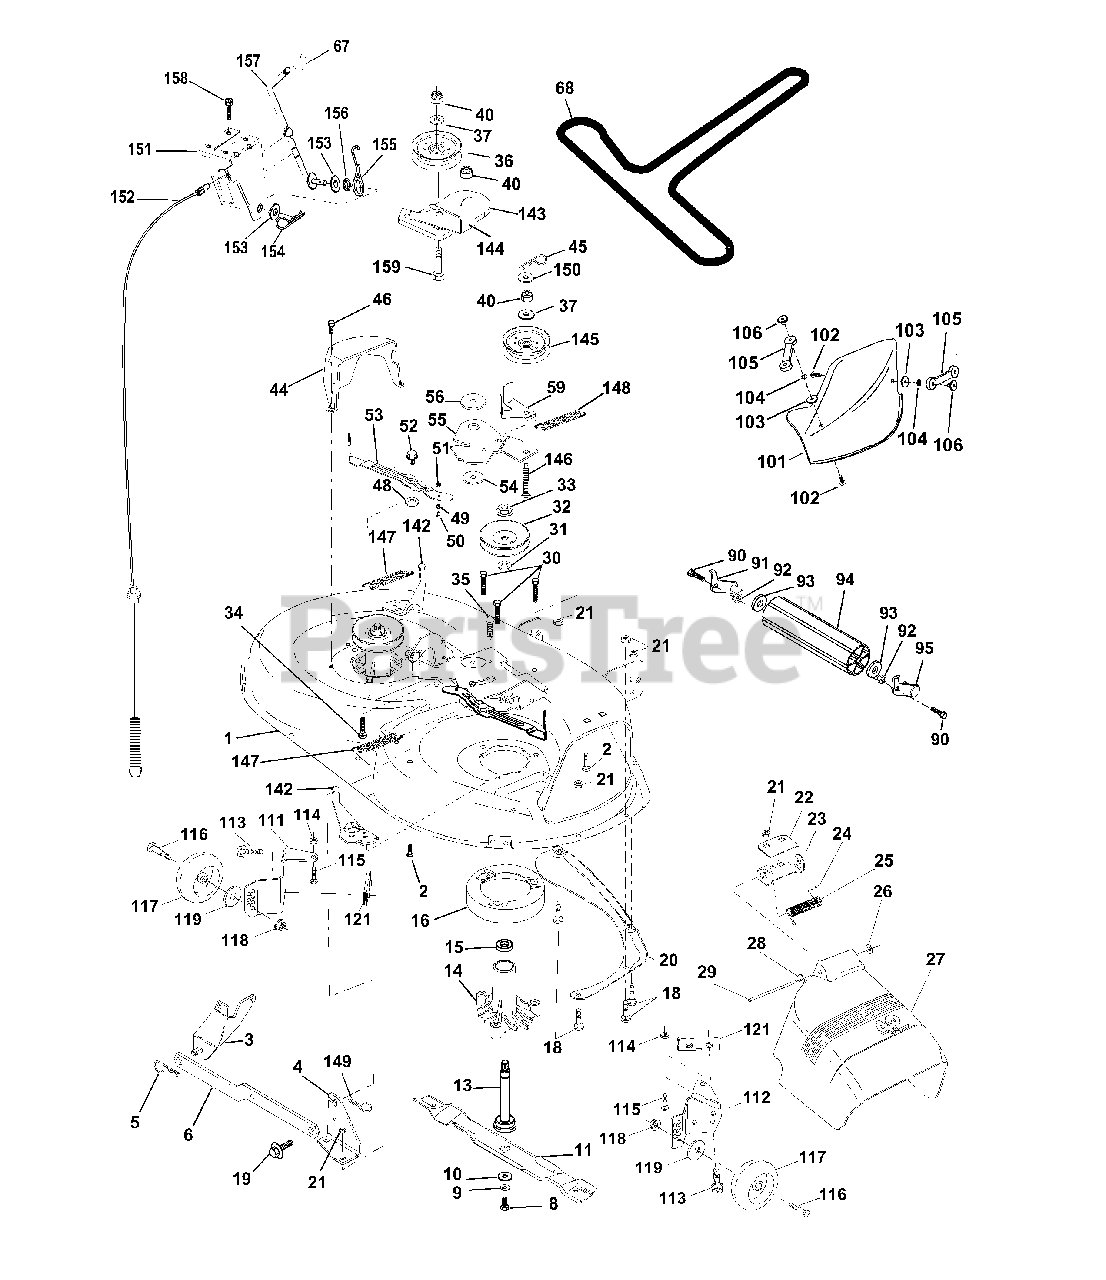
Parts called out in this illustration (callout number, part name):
1	Mower Deck Assembly, 42"
2	Bolt
3	Bracket Asm Fr. Sway Bar 3/42
4	Bracket Asm Deck 42" Sway Bar
5	Retainer Spring
6	Arm, Suspension, Rear
8	Bolt 3/8-24 x 25 Grade 8 patched
9	Washer, Lock
10	Washer,Hardened
11	Blade, Mulching 42"
11	Blade Mower 42" Hi-Lift
13	Shaft Assembly, Mandrel, Vented
14	Housing, Mandrel, Vented
15	Bearing, Ball, Mandrel
16	Stripper, Mandrel Deck
18	Bolt, Carriage 5/16-18 x 5/8
19	Bolt, Shoulder
20	Baffle, Vortex
21	Nut
22	Stiffener Bracket
23	Bracket, Deflector Mower 42"
24	Cap, Sleeve 80 x 112 Blk Mower
25	Spring, Torsion, Deflector 2 52
26	Nut, Push Phos & Oil
27	Shield, Deflector 42" Blk
28	Washer 11/32 x 5/8 x 16 Gauge
29	Rod, Hinge 42" 6 75 W/G
30	Screw Thdrol Washer Head
31	Washer, Spacer Mower Vented
32	Pulley, Mandrel
33	Nut, Toplock 9/16
34	Bolt
35	Fastener, Christmas Tree
36	Pulley, Idler, Flat
37	Washer 13/32 x 13/16 x 16 Gauge
40	Nut
44	Guard, Mandrel, LH
45	Retainer
46	Screw, Thdrol 1/4-20 x 5/8 T
48	Washer,Hardened
49	Roller Assembly, Cam Follower
50	Bolt, Shoulder #10-24 Grade 5
51	Locknut
52	Bolt, Shoulder 5/16-18 UNC
53	Arm Assembly, Pad, Brake
54	Washer,Hardened
55	Arm, Idler
56	Spacer, Retainer
59	Guard TUV Idler
67	Knob
68	V-Belt, 42" Mower
90	Bolt Fin Hex 3/8-16 Unc x 1
91	Bracket Asm. Noseroller LH
92	Nut, Lock, Hex W/Ins 3/8-16 UNC
93	Washer 17/32 x 7/8 x 16 Ga.
94	Roller, Nose
95	Bracket Asm. Noseroller RH
101	Mulcher Cover
102	Screw
103	Washer, Flat
104	Washer, Lock
105	Latch Assembly
106	Nut, Weld
111	Bracket, Gauge, Wheel LH
112	Bracket, Gauge, Wheel RH
113	Screw Tapping 5/16-18 Unc
114	Nut, Keps 5/16 - 18 UNC
115	Bolt, Carriage 5/16-18 x 1/2
116	Bolt, Shoulder
117	Wheel, Gauge
118	Nut Centerlock 3/8-16
119	Washer 3/8 x 7/8 x 14 Ga.
121	Bracket, Extruded
142	Arm Spring Brake Mower
143	Bracket Arm Idler 42"
144	Keeper Belt 42" Clutch Cable
145	Pulley Idler Flat
146	Bolt Carriage Idler
147	Spring Extension
148	Spring Return Idler
149	Retainer Spring Yellow
150	Washer 9/32 x 3/4 x 16 Ga.
151	Bracket Clutch Cable
152	Clutch Cable 42"
153	Washer Flat 3/8" Type B
154	Spring Retainer
155	Spring Retention LVR CLTCH CAB
156	Spacer Clutch Cable
157	Rod Clutch Cable 3/8"
158	Screw Hex Thd Cut 1/4-20 x 5/8
159	Bolt Rdhd Sqn 3/8-16 UNC x 1-3/4
